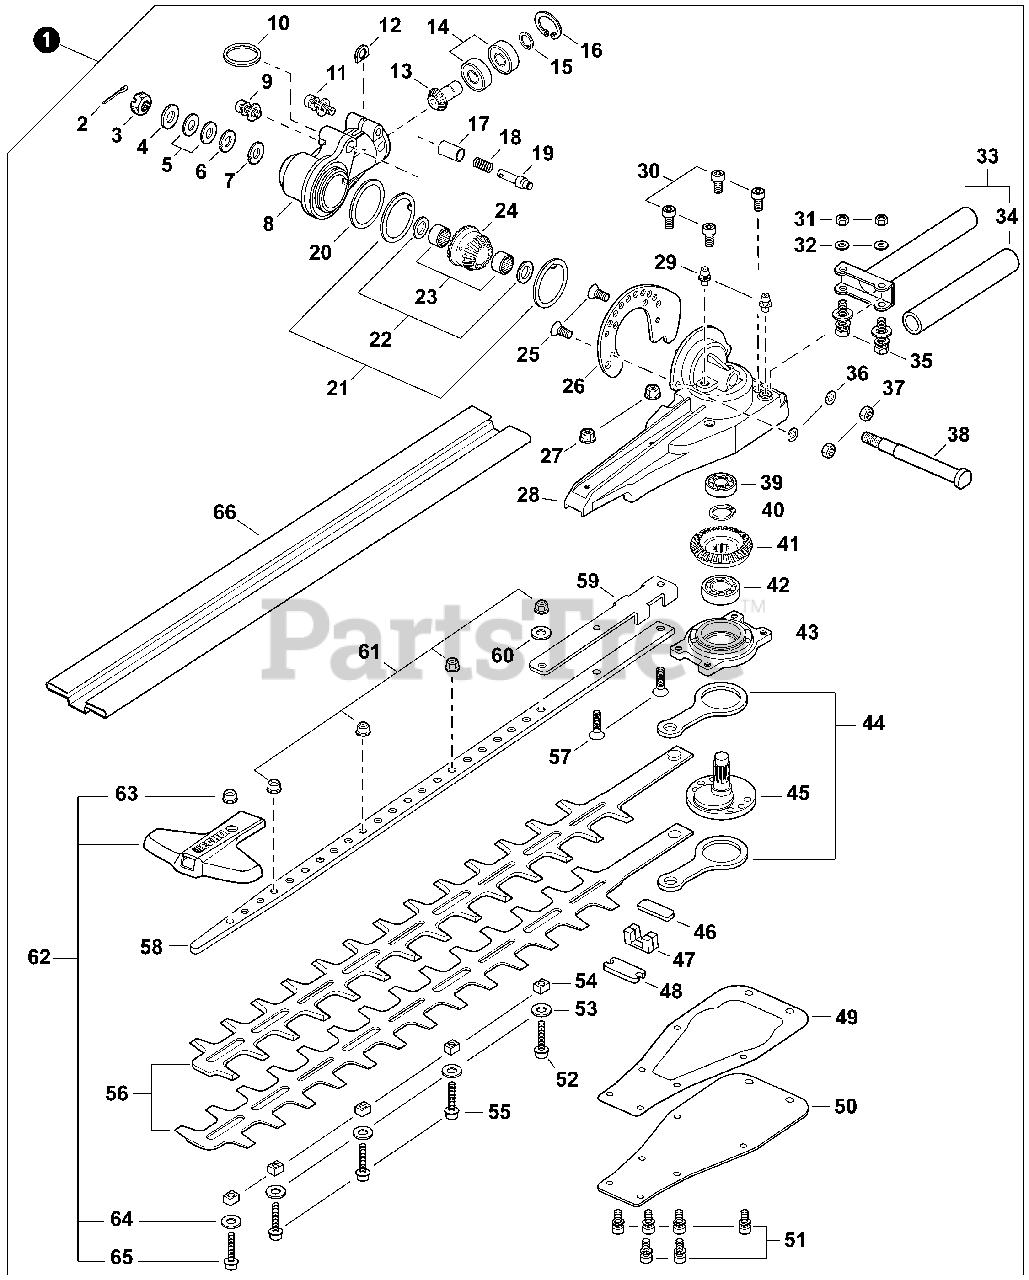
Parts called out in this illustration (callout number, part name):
1	CUTTING HEAD KIT
2	PIN, COTTER 6×18
4	WASHER 8
5	WASHER, CONICAL
7	GASKET, GEAR CASE
8	CASE, GEAR
9	BOLT 5×12
10	RING, RETAINING
11	BOLT 5×25
13	GEAR, BEVEL
14	BEARING, BALL 6900
15	RING, SNAP
16	RING, SNAP Ø22
17	COLLAR 8
18	SPRING, COMPRESSION
19	LINCHPIN
20	O-RING 32
22	WASHER 10
23	BEARING, NEEDLE 10
24	GEAR, BEVEL
25	SCREW 4×12
26	BRACKET, ADJUSTOR
27	NUT, FLANGE M5
28	CASE, GEAR - CUTTER
29	FITTING, GREASE
30	BOLT 5×8
31	NUT, LOCK M5
32	WASHER, FLAT 5.5×10×0.8
33	ADJUSTOR ASSY, HANDLE
34	GRIP, HANDLE
35	BOLT 5×28
36	WASHER, SPRING 4 MM
37	NUT, LOCK 4
38	SHAFT, GEAR
39	BEARING, BALL 6900
40	RING, SNAP 11
41	GEAR, BEVEL
42	BEARING, BALL 6001
43	HOLDER, BEARING
44	ROD, CONNECTING
46	GUIDE, BLADE
48	GUIDE, BLADE
49	GASKET, GEAR CASE
50	COVER, GEAR CASE
51	BOLT 4×14
52	BOLT, FLANGE 5×22
53	WASHER 5
54	GUIDE, BLADE 5
55	BOLT 5×20
57	BOLT 5×20
58	SUPPORT, BLADE L= 558.3 MM
59	GUIDE, BLADE
60	WASHER 6.5×15.5×0.6
61	NUT, FLANGE M5
62	TIP GUARD KIT
63	NUT, FLANGE M5
64	WASHER 5
65	BOLT 5×20
66	SCABBARD
